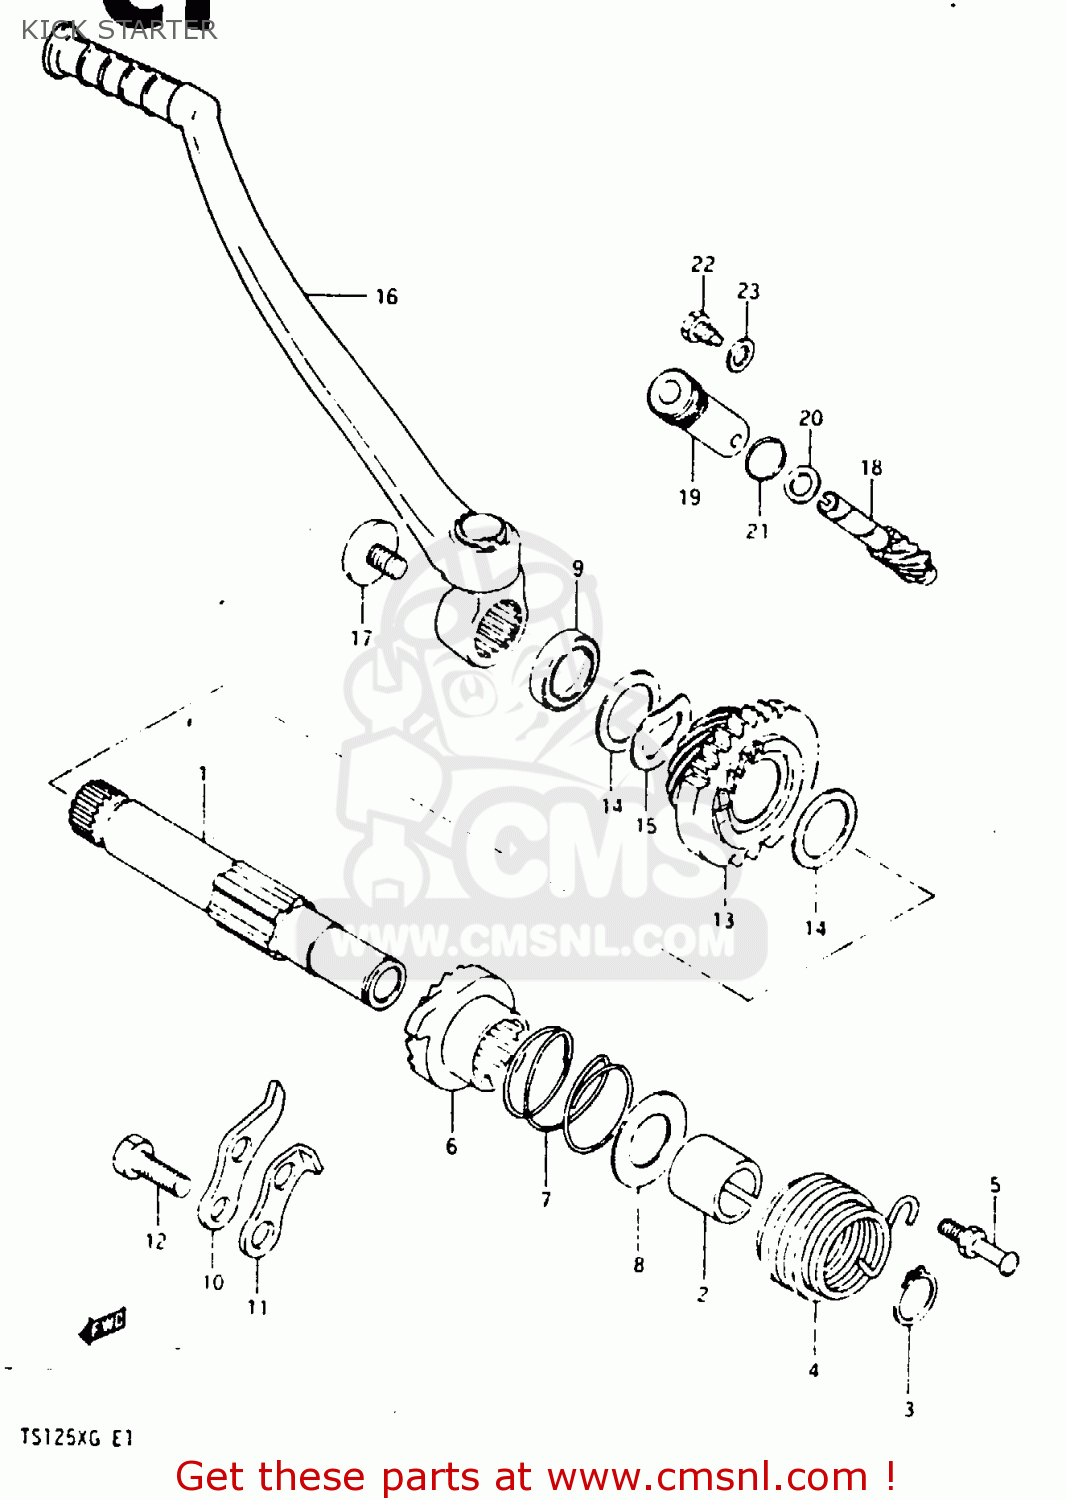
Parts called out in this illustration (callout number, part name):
1	SHAFT, KICK STARTER
2	GUIDE,KICK STARTER SFT SPRING
3	CIRCLIP,16MM
4	SPRING
5	BOLT,KICK SHAFT SPRING
6	STARTER,KICK
7	SPRING
8	WASHER
9	SEAL,OIL(20X27X5)
10	GUIDE,KICK STARTER
11	STOPPER,KICK STARTER
12	BOLT(8X20)
13	GEAR, DRIVE (NT:27/14)
14	WASHER,THRUST
15	WASHER
16	LEVER ASSY, KICK STARTER
17	BOLT 8X14
18	GEAR, TACHO. DRIVEN (NT:11)
19	SLEEVE,TACHOMETER DRIVE GEAR
20	WASHER(8X13.7X1)
21	O RING(D:1.3,ID:9.6)
22	BOLT
23	GASKET(6.2X11X1).2 (NAS)
